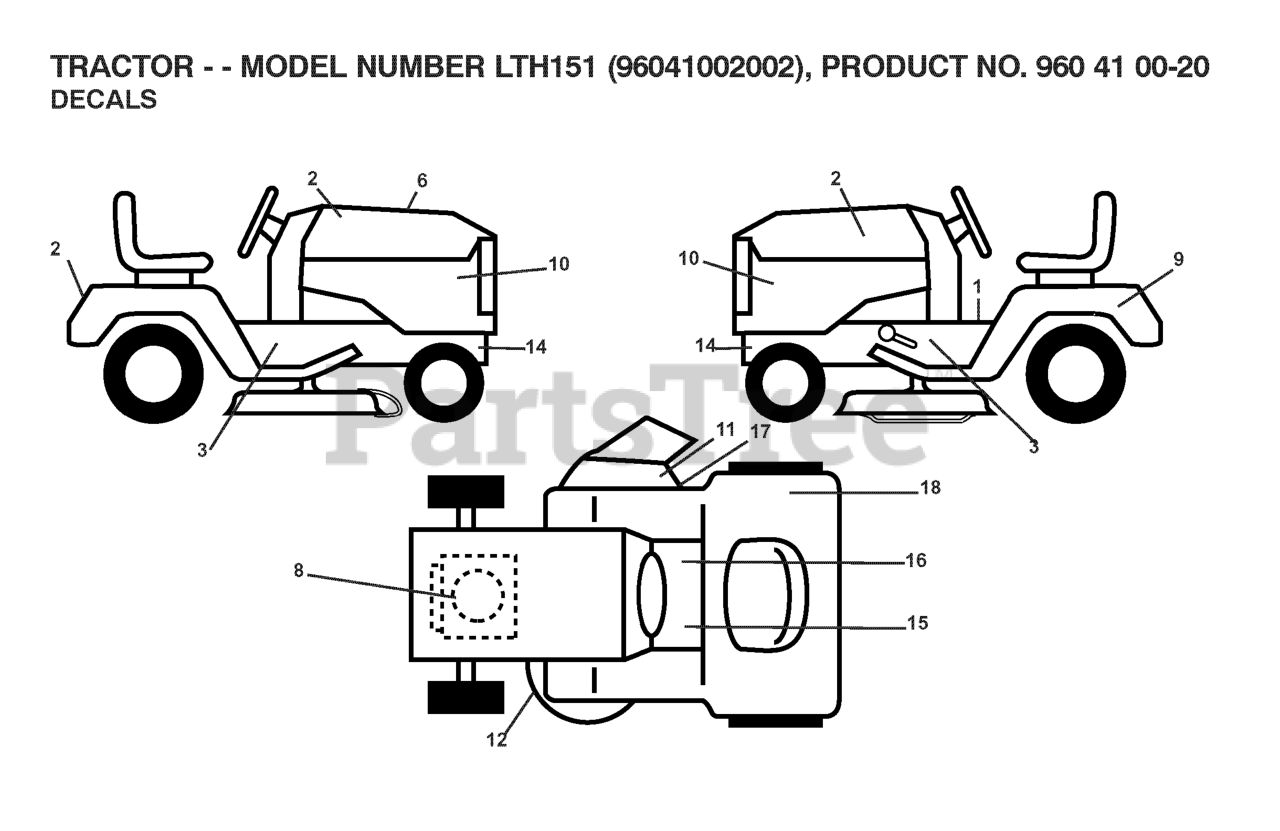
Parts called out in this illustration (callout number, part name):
1	LABEL
2	DECAL.HOOD.NAMELOGO.HUSQ
8	DECAL
9	DECAL BTRY SYMBOLS
10	DECAL SIDE PANEL
11	DECAL.INTERNATIONL.CUTFINGER
12	DECAL.V-BELT.SCHEMATIC.36/38/9
15	DECAL
16	DECAL PARK BRAKE
17	DECAL, DEFLECT WARNING
18	Decal, Fender 100 DB/CE
